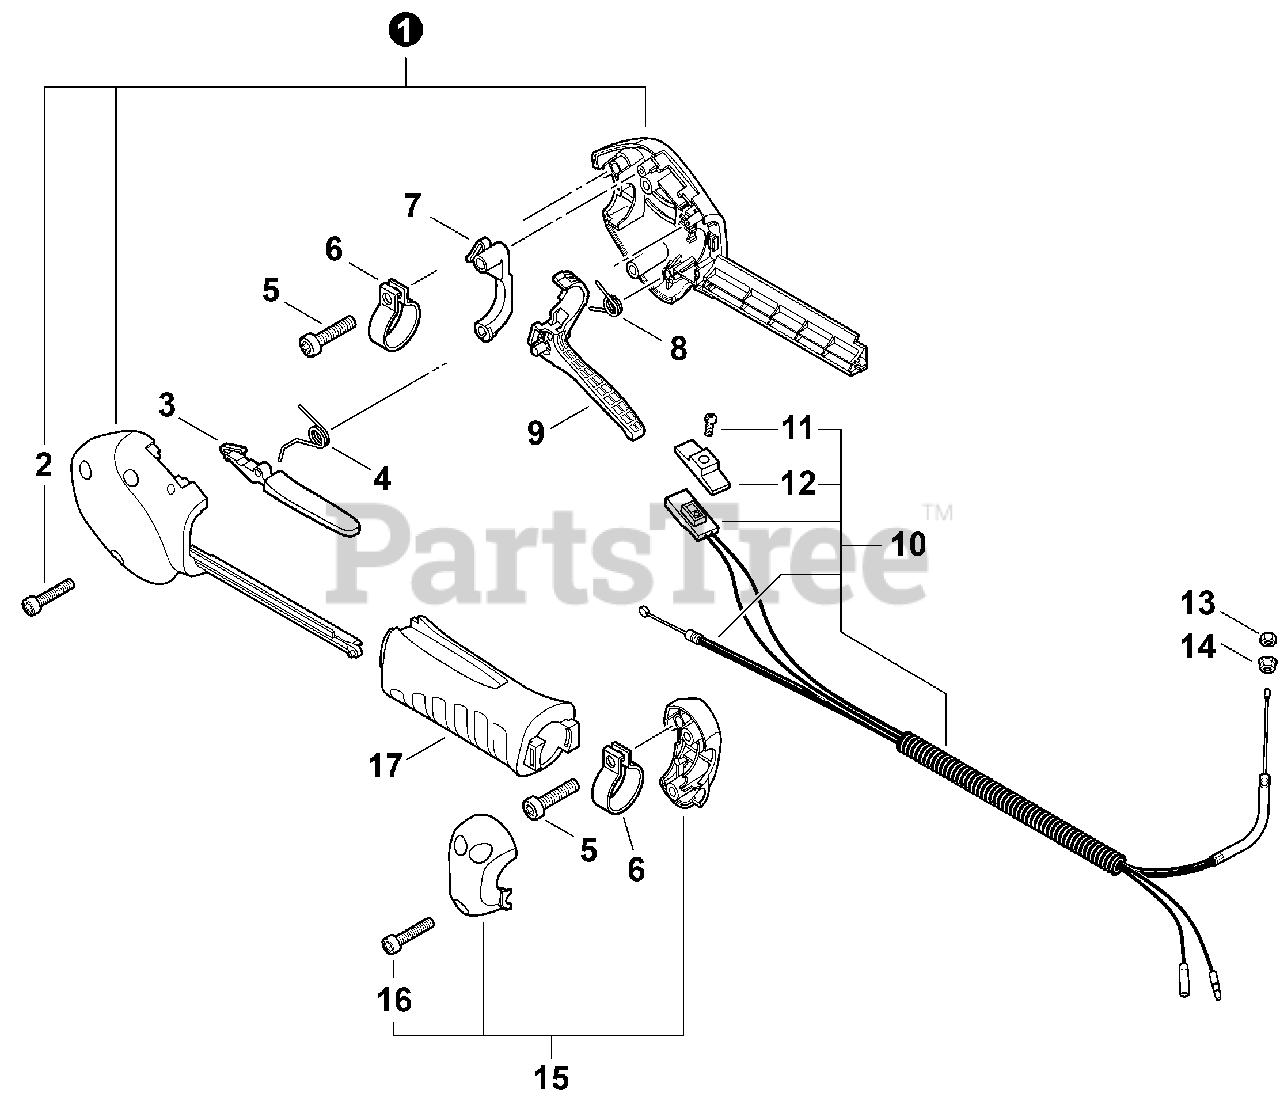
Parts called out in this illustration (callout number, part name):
1	CONTROL HANDLE KIT
2	SCREW - 4×20 -- TAPPING
3	LEVER,THROTTLE LOCKOUT
4	SPRING, LEVER RETURN
5	SCREW - 5×20
7	LOCKOUT,TRIGGER
8	SPRING,TRIGGER
9	TRIGGER,THROTTLE
10	CONTROL CABLE ASSY
11	SCREW - 3×10
12	KNOB, SWITCH - ORANGE
14	NUT - 6 -- FLANGE
15	HANDLE FIXTURE KIT
16	SCREW - 4×20 -- TAPPING
17	GRIP, HANDLE
